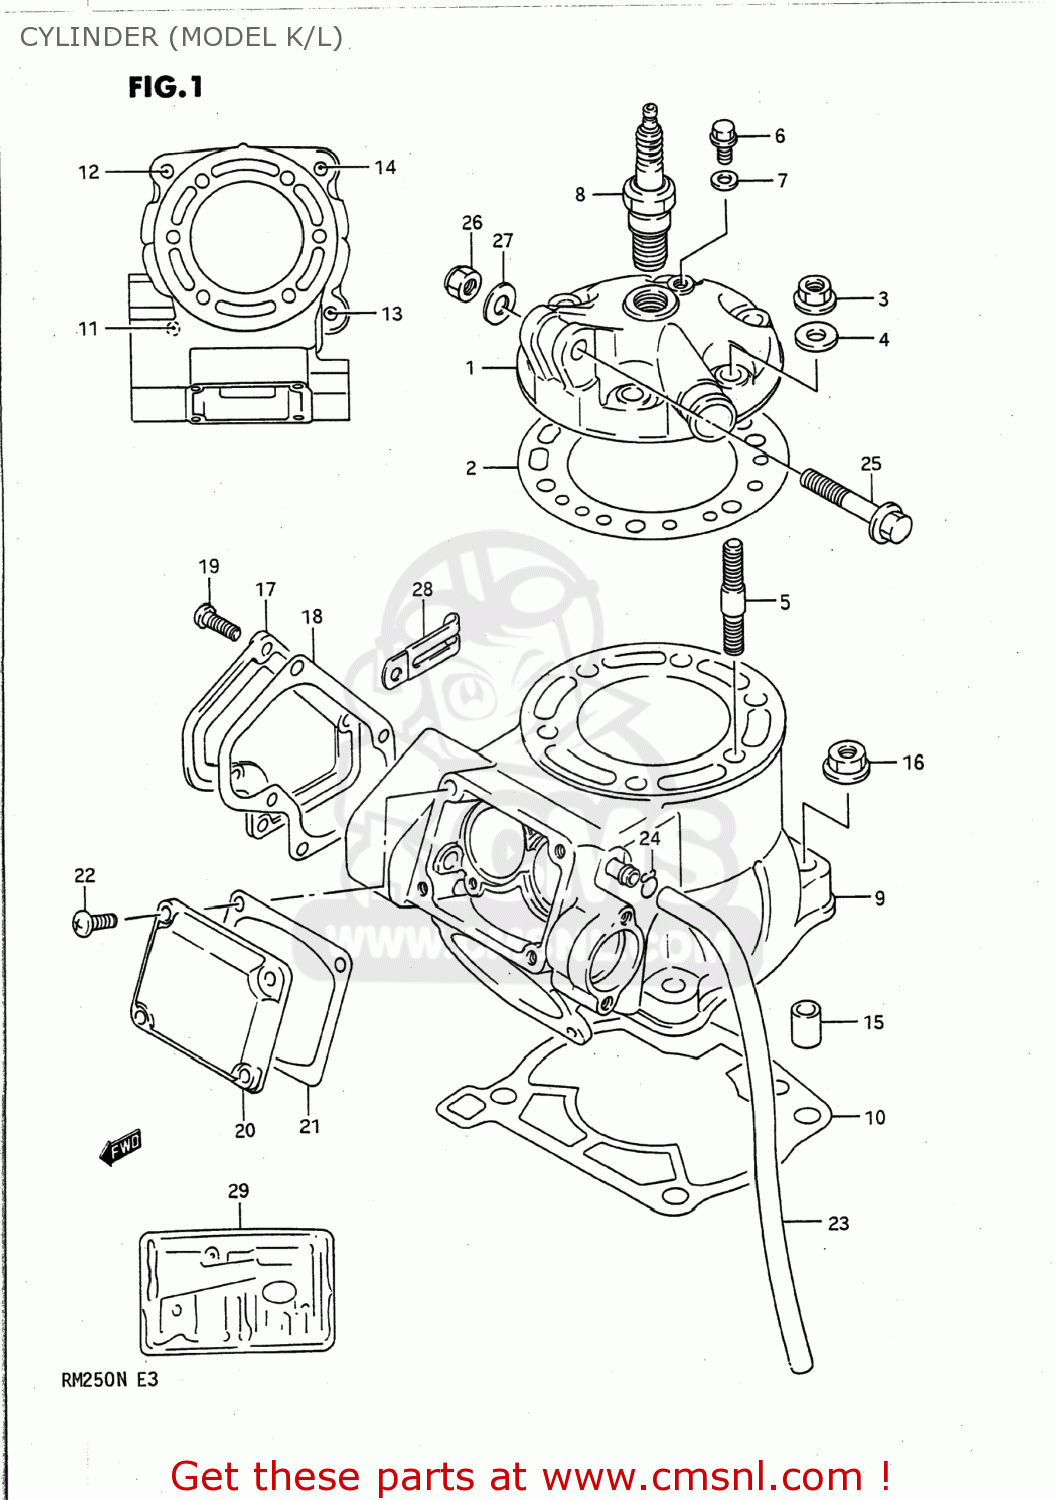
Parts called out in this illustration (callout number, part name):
1	HEAD,CYLINDER
2	GASKET,CYLINDER HEAD (MCA)
3	NUT
4	WASHER
5	BOLT,STUD
6	UNION
7	GASKET(6.2X11X1).2 (NAS)
8	PLUG,SPARK(NGK B-8EN)
9	CYLINDER
10	GASKET,CYLINDER (NAS)
11	STUD 10X30
12	STUD BOLT
13	STUD BOLT (L:40)
14	STUD BOLT (L:45)
15	PIN
16	NUT
17	COVER,CYLINDER NO.1
18	GASKET,CYLINDER COVER (NAS)
19	SCREW
20	COVER,CYLINDER
21	GASKET,CYLINDER COVER (NAS)
22	SCREW
23	HOSE
24	CLIP
25	BOLT 8X45
26	NUT
27	WASHER
28	CLAMP
29	GASKET SET
